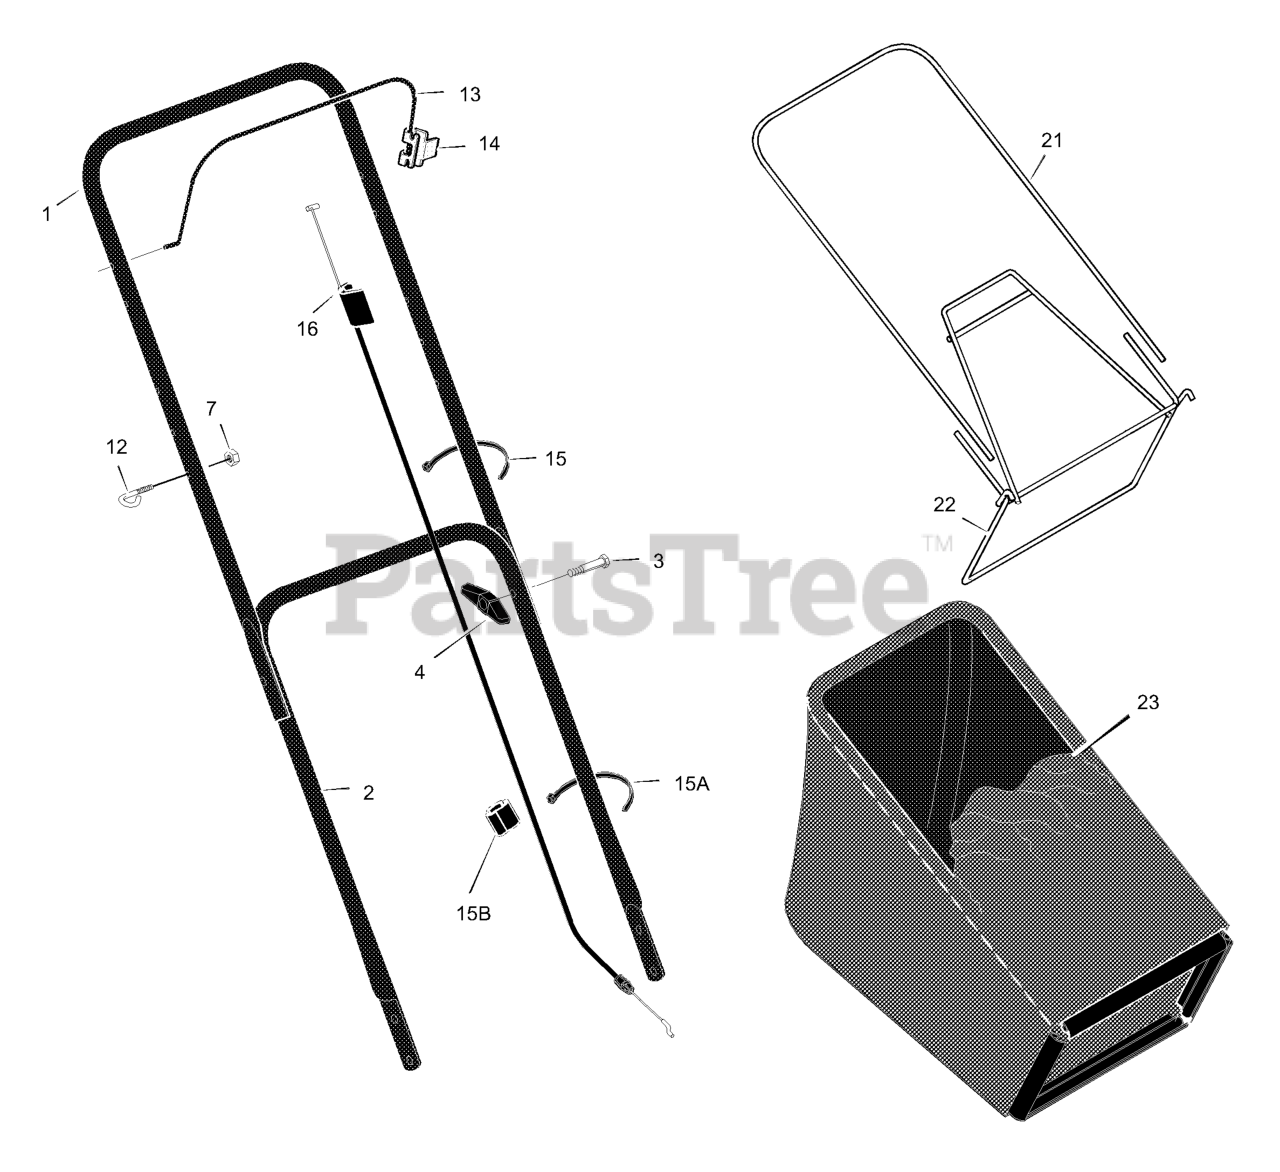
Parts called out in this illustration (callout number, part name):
1	Handle, Upper (Black)
2	Handle, Lower (Black)
4	Knob, Plastic
7	Locknut
12	Guide, Rope
13	Engine Stop Lever
14	Bracket, Stop Lever
15A	Tie, Cable
15B	Fastener, Single Cable
16	Engine Stop Cable
17	Pin, Hair
21	Frame, Top
22	Frame Assembly
23	Bag, Cloth
